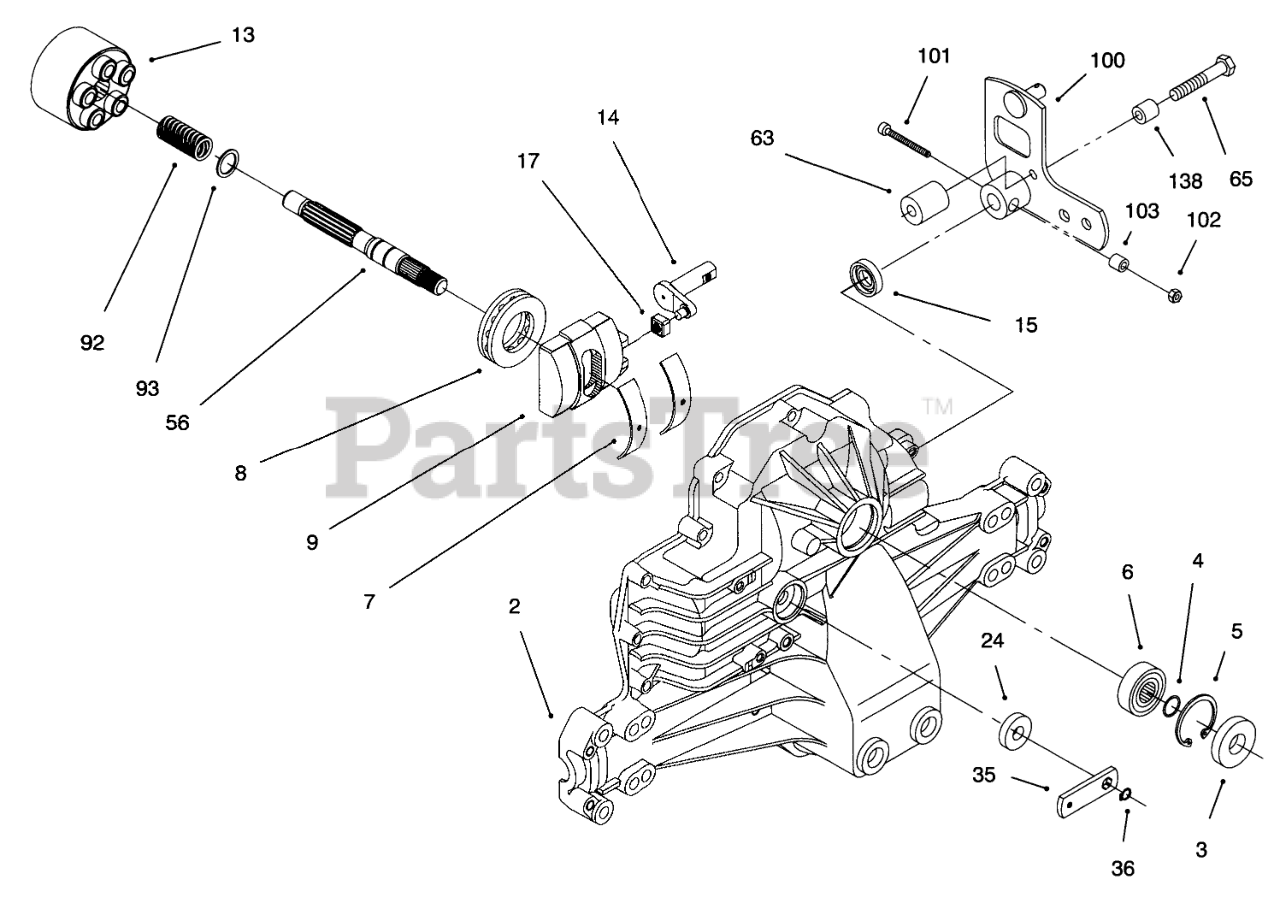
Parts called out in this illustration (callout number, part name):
2	ASM - HOUSING UPPER
3	SEAL-LIP
4	RING-WIRE, RETAINING
5	RING-RETAINING
6	BEARING-SHAFT, BALL
7	BEARING-CRADLE
8	BEARING-THRUST
9	SWASHPLATE-VARIABLE
13	BLOCK - CYCLINDER ASM
14	ARM-TRUNION
15	SEAL-LIP
17	GUIDE-SLOT
24	SEAL-LIP
35	ARM - BYPASS
36	RING-RETAINING
56	SHAFT - INPUT
65	Bolt
92	SPRING-BLOCK
93	WASHER-THRUST
100	Control Arm Assembly
101	Socket Head Cap Screw
102	Nut
